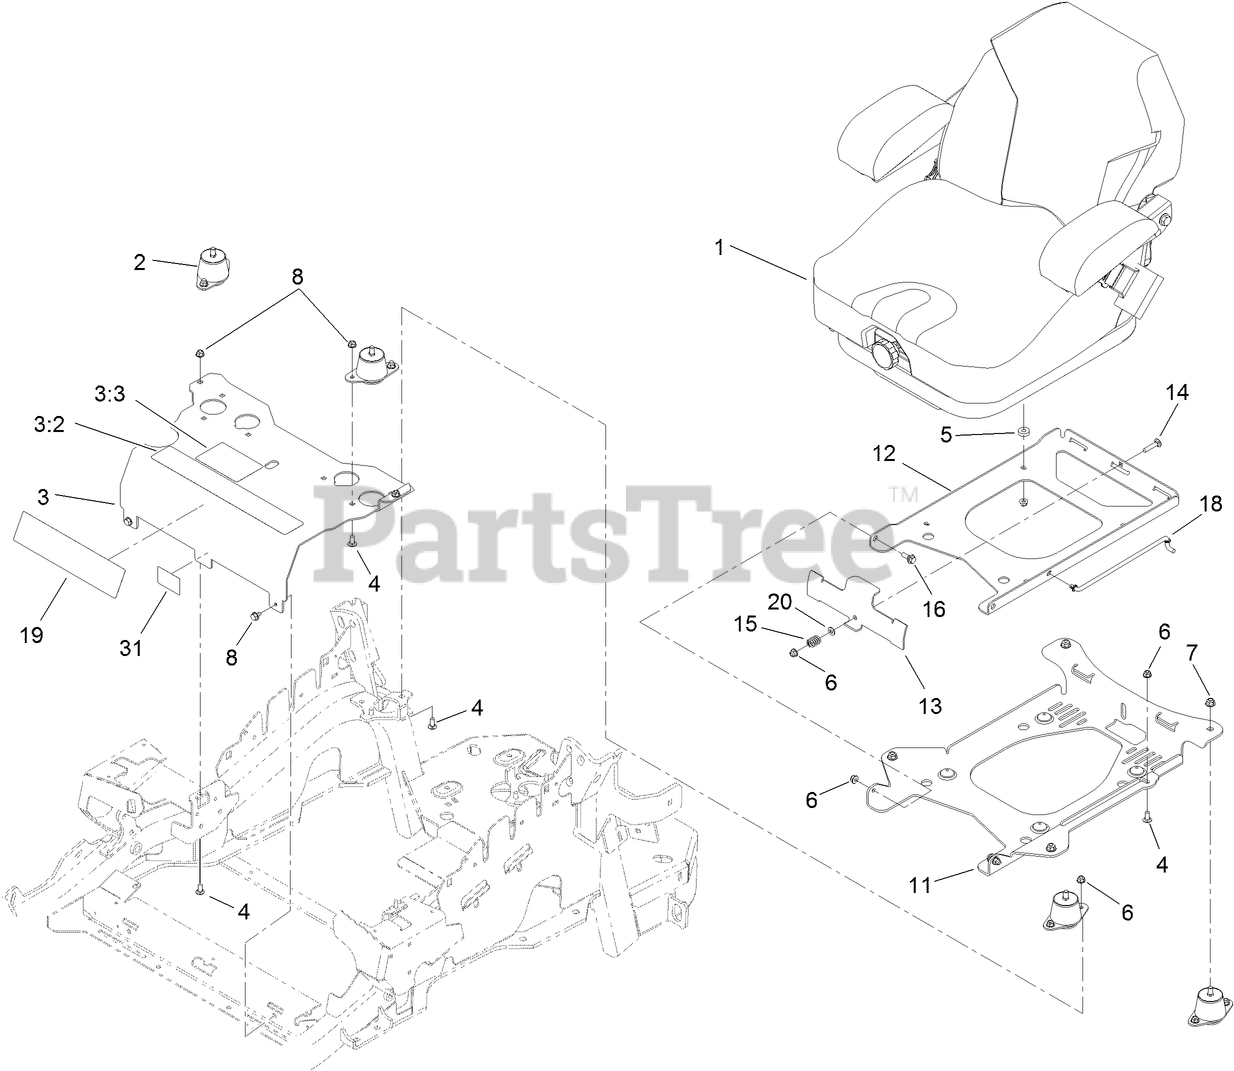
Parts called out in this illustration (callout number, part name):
1	SUSPENSION SEAT ASM
2	ISOLATOR-SEAT
3	MOUNT-SEAT
3:2	DECAL-CONSOLE
3:3	DECAL-SERVICE AID
4	SCREW-CARR
5	SPACER-PIN, MOUNTING
6	NUT-HF, NI
7	NUT-HF, NI
8	SCREW
11	PLATE-TILT, SEAT SUPPORT
12	PLATE-FRAME, SEAT
13	PLATE-LATCH, SEAT
14	BOLT-CARR
15	SPRING-COMPRESSION
16	SCREW-SHOULDER
18	ROD-PROP
20	WASHER-PLAIN
31	DECAL-EFI
